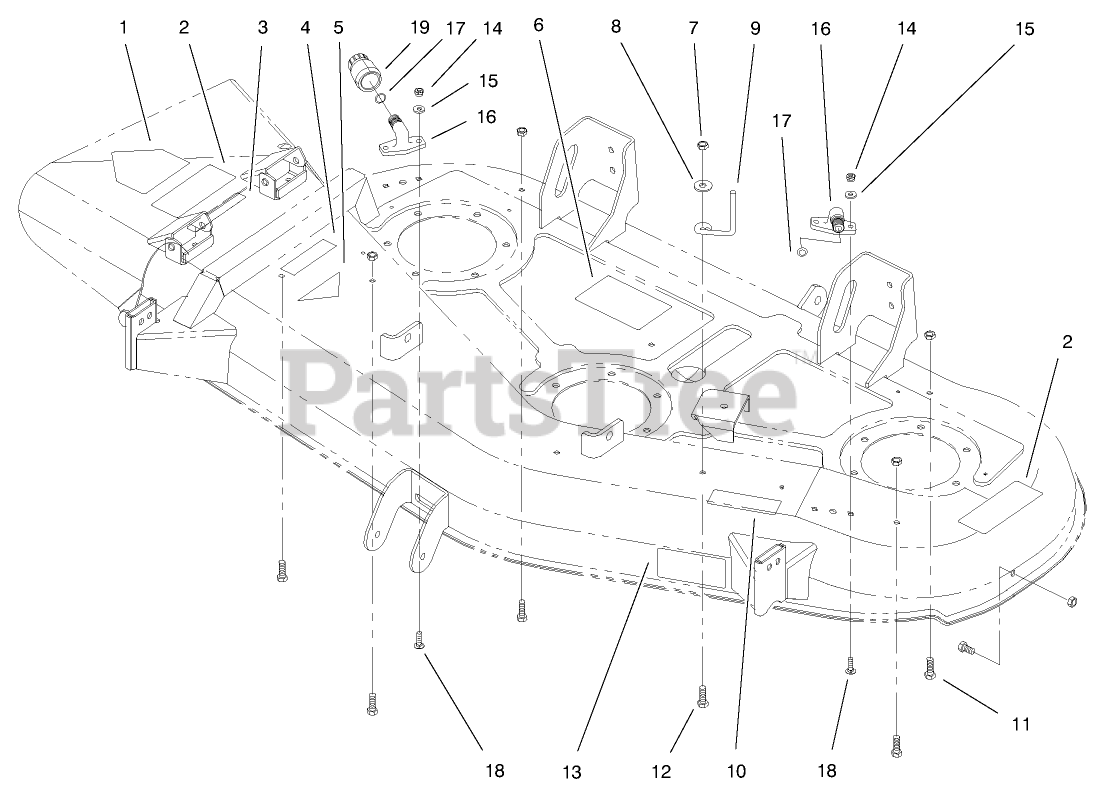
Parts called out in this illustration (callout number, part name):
1	DECAL-DANGER
2	DECAL-DANGER
3	DECAL-CAUTION
6	DECAL-BELT ROUTING
7	NUT-LOCK, NI
8	WASHER-PLAIN
9	GUIDE-BELT
10	DECAL-BELT ROUTING
11	SCREW-HH
12	SCREW-HH
13	DECAL-ADJUSTMENT, WHEEL
14	NUT-LOCK, NI
15	WASHER-FLAT
17	O-RING
18	BOLT-CARR
19	CONNECTOR-HOSE
